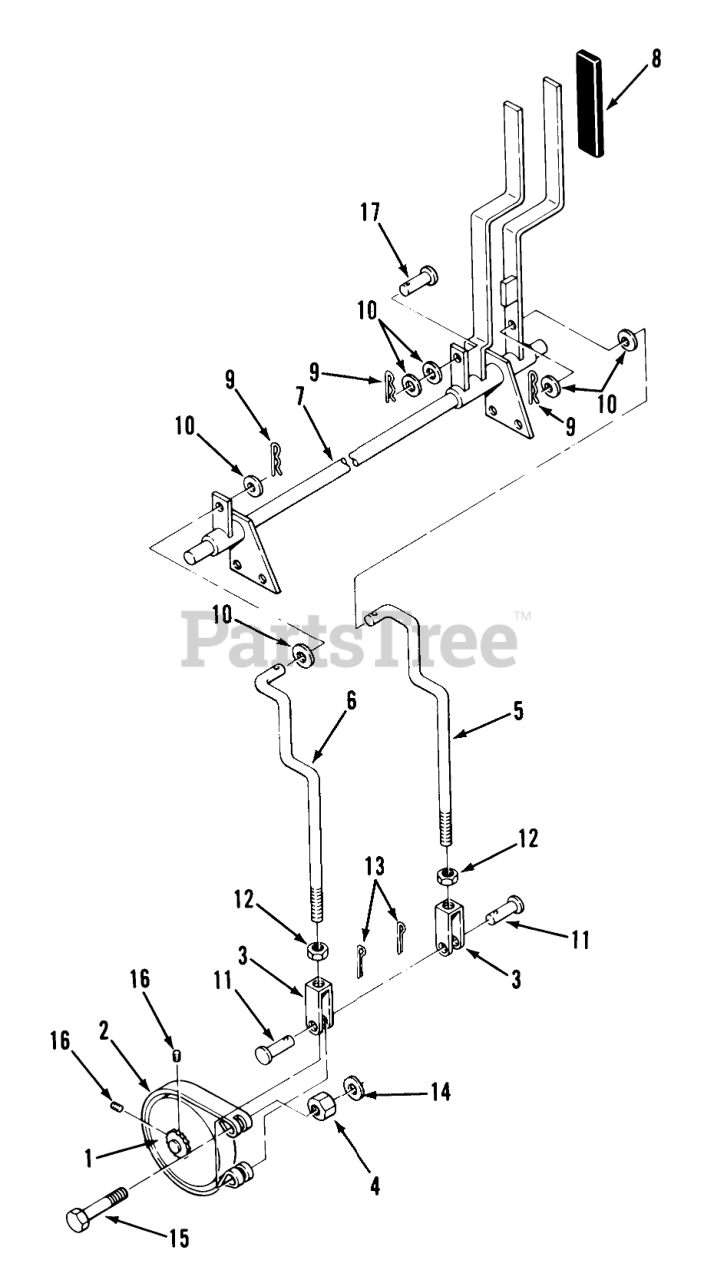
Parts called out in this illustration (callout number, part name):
1	Sprocket and Drum #50
2	Brake Bands
3	YOKE-BRAKE 20214-1
4	Coupling Rod Nut 3/8-16 x 7/8
5	LH BRAKE ROD 20278-1
6	Brake Rod RH
7	Brake Rod Assembly
8	GRIP BRAKE20258-K
9	HAIRPIN
10	WASHER
11	Clevis Pin 5/16 x 1 1/4
12	Nut-Lock
13	Cotter Pin
14	Washer
15	BOLT
16	SCREW-SET
17	Clevis Pin 5/16 x 7/8
